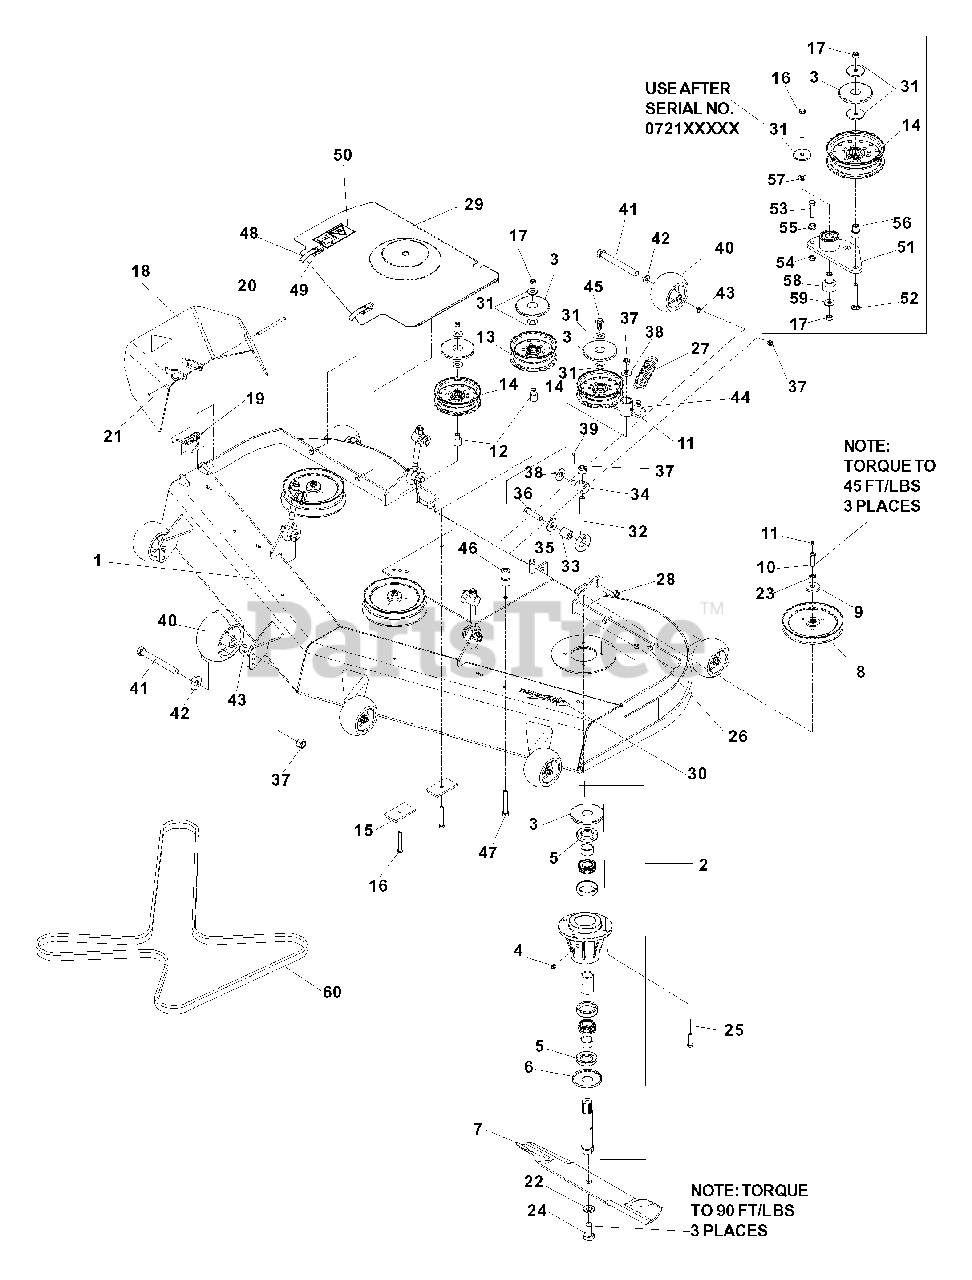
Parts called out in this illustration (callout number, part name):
1	DECK W/DECALS
2	SPINDLE
3	DUST CAP, TOP
4	PLUG, VENTED
5	SEAL, SHAFT
6	DUST CAP, BOTTOM
7	BLADE, 25"
8	PULLEY, 72"
9	HEAVY WASHER
10	HCS, 7/16 -20 x 1 1/2, GR8, SPEC.
11	ZERK
12	IDLER BUSHING
13	IDLER PULLEY (TALL)
14	IDLER PULLEY
15	PAD
16	HCS, 3/8 -16 x 3,
17	NUT, 3/8 -16, NYLOC
19	SPRING, TORSION
20	PIN, CLEVIS, 5/16 x 11/16
21	PIN, COTTER, 1/8 x 3/4
22	LOCKWASHER, 5/8
23	LOCKWASHER, 7/16
24	HCS, 5/8 -18 x 1 1/4,
25	HCS, 5/16 -18 x 1 1/4,
26	NUT, 5/16 -18, NYLOC
28	NUT, 7/16 -14, CTRLK, GR A
29	BELT SHIELD, RIGHT
29	BELT SHIELD, LEFT
30	DECAL, TUNNEL RAM
31	WASHER, 3/8, SPECIAL
35	SPRING WASHER, 1/2
36	HCS, 7/16 -14 x 1 3/4,
37	NUT, 1/2, NYLOC
38	WASHER, 1/2
39	PIN, COTTER, 1/8 x 1
40	WHEEL GAUGE
41	HCS, 1/2 -13 x 4 1/2
42	WASHER, 1/2
43	NUT, 1/2 -13
45	HCS, 3/8 -16 x 1 1/4,
46	PIVOT BUSHING
47	HCS, 1/2 -13 x 3 1/4,
48	DRAW LATCH
49	BLIND RIVET
50	DECAL, EURO, SEVERING
51	ARM, IDLER, W/BEARINGS
52	RHSNB, 3/8 -16 x 2 3/4,
53	HCS, 3/8 -16 x 1 1/2, GR8
54	NUT, 3/8 -16, JAM
55	NUT, 3/8 -16, WHIZLK
56	BUSHING, IDLER
57	WASHER, 3/8 , SAE
58	PIVOT, BEARING
59	WASHER, 3/8
